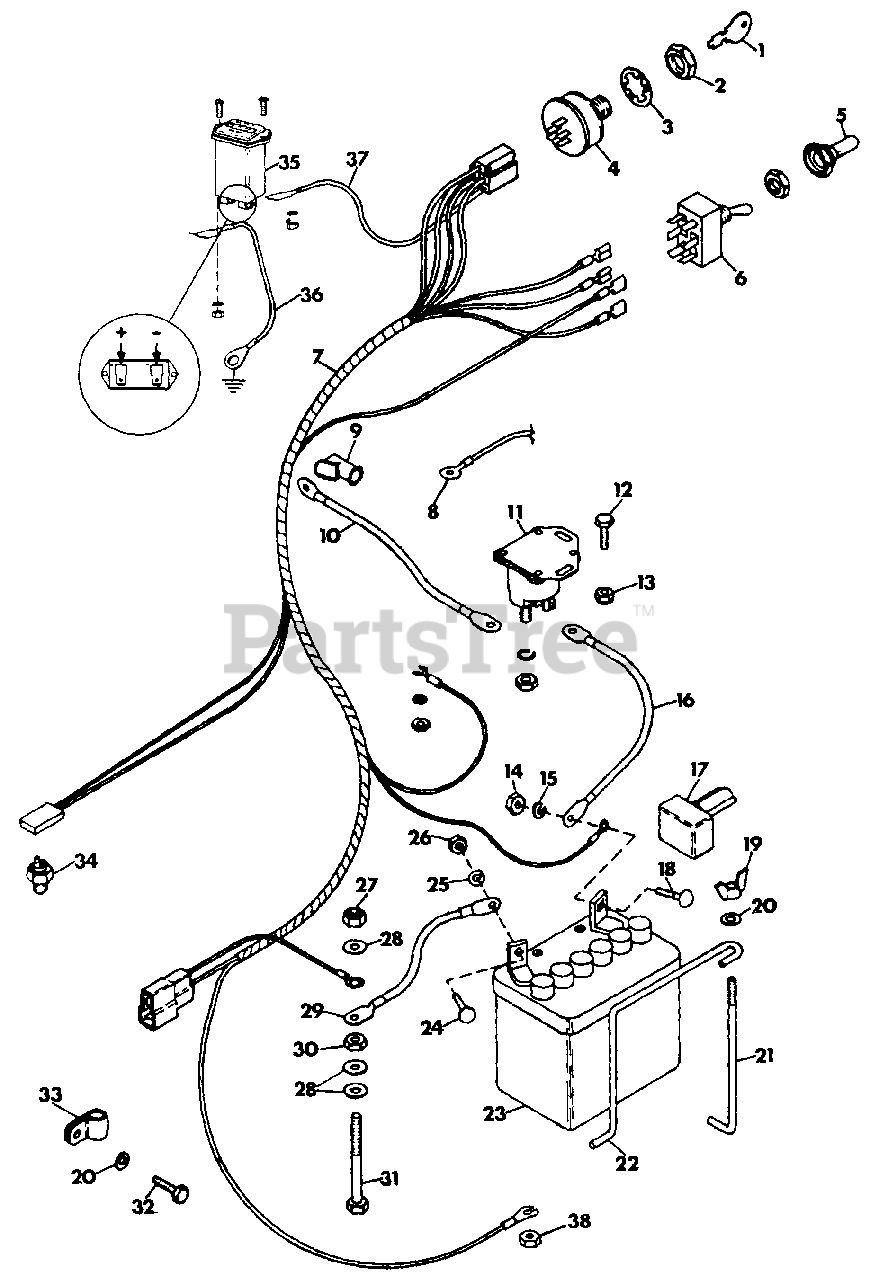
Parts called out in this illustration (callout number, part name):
1	KEY, IGNITION SWITCH
2	NUT, JAM 9/16-24
3	WASHER, LOCK
4	SWITCH, IGNITION
5	BOOT, TOGGLE SWITCH
6	SWITCH, TOGGLE
7	HARNESS, WIRING MAIN
8	TERMINAL, RING TONGUE
9	BOOT, BATTERY CABLE
10	CABLE, SOLENOID TO STARTER
11	SWITCH, MAGNETIC
12	BOLT, HEX 1/4-20X.625
13	NUT, SPEED 1/4-20
14	NUT, HEX 5/16-18
15	WASHER, LOCK 5/16 REG.
16	CABLE, BATTERY TO SOLENOID
17	BOOT, BATTERY CABLE
18	BOLT, 5/16-18X.625 RD HD SQ NK
19	NUT, WING 1/4-20
20	WASHER, FLAT .281X.625X.065
21	HOOK, BATTERY HOLD DOWN
22	BRACKET, BATTERY HOLD DOWN
23	BATTERY, 12 VOLT
24	BOLT, 1/4-20X.625 RD HD SQ NK
25	WASHER, LOCK 1/4
26	NUT, HEX 1/4-20
27	NUT, LOCK 5/16-18
28	WASHER, FLAT .344X.688X.065
29	CABLE, NEGATIVE BATTERY
30	NUT, HEX 5/16-18
31	BOLT, HEX 5/16-18X2.00
32	BOLT, HEX 1/4-20X1.00
33	CLAMP
34	SWITCH, NEUTRAL START
35	HOURMETER
36	WIRE, INSTRUMENT PANEL
37	WIRE, HOURMETER
38	NUT, HEX 8-32
